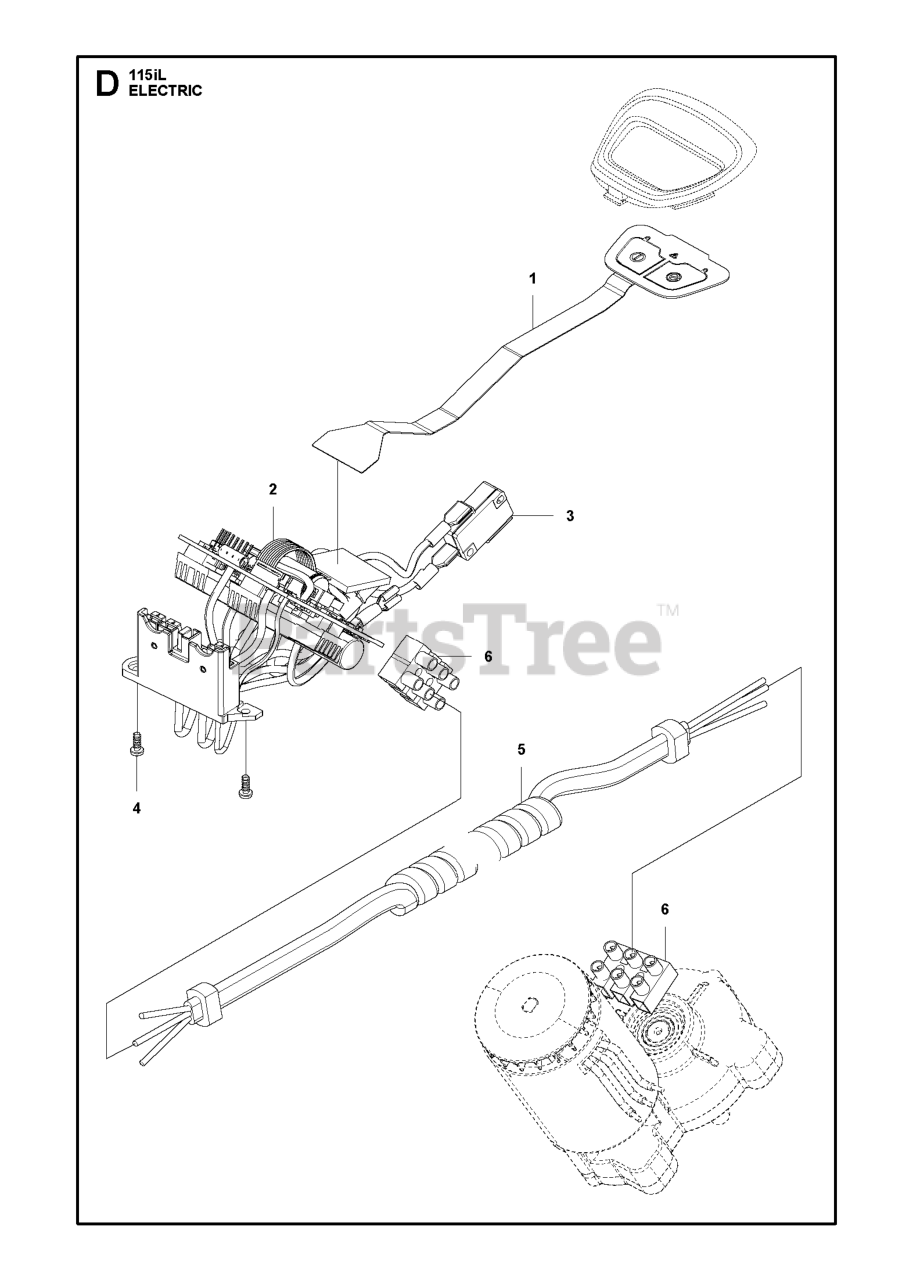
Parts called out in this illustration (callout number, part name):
1	KEYPAD TRIMMER 36V
2	CONTROL UNIT CONTROL UNIT BLDC
3	MICRO SWITCH
4	SCREW ST3X8
5	CABLE SPIRAL CABLE ASSEMBLY 36
6	CONNECTOR SMALL
